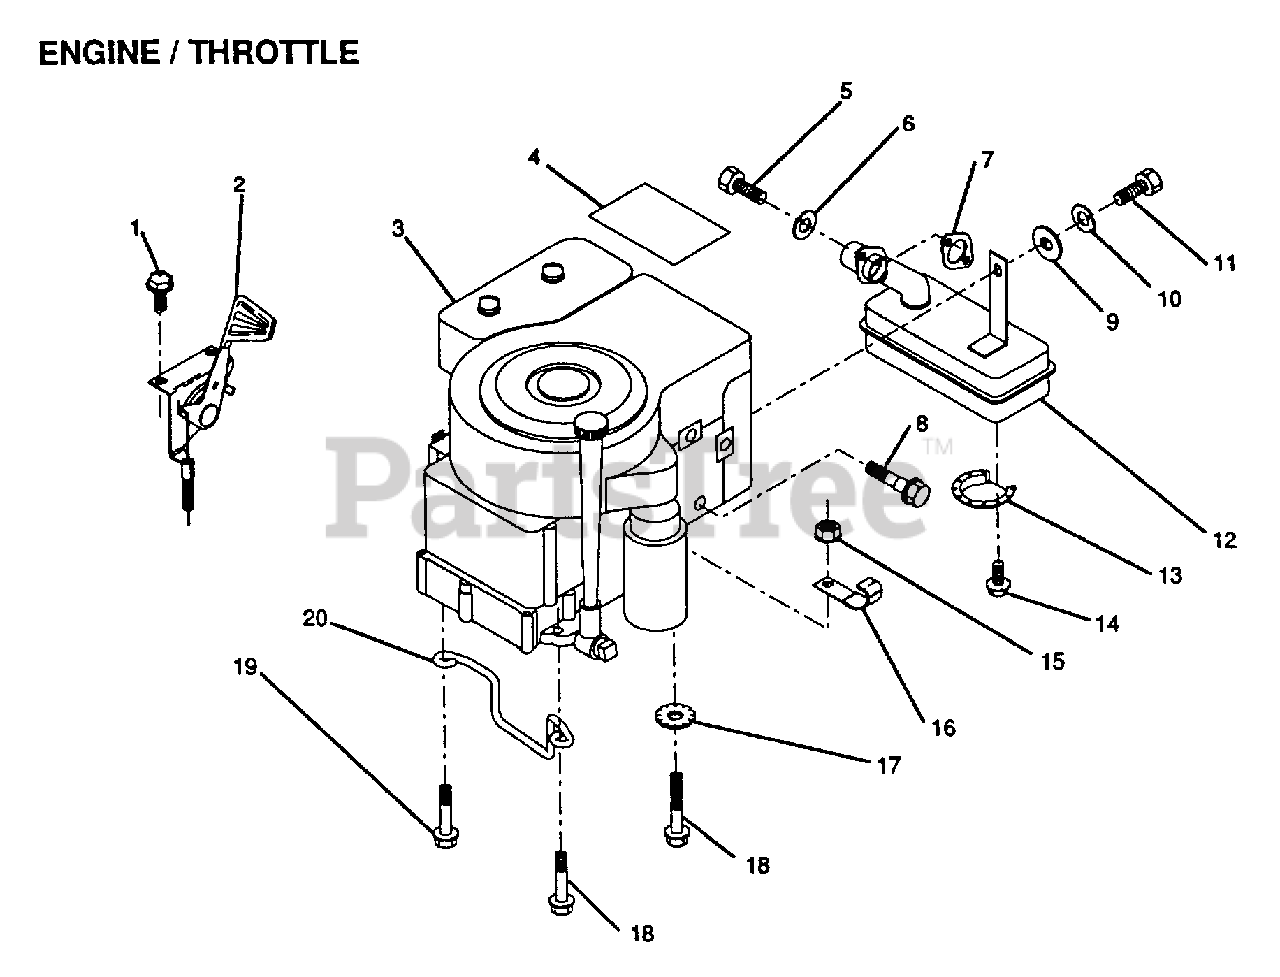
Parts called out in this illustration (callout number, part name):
1	SCREW
3	ENGINE BRIGGS AND STRATTON
4	DECAL.ENG.271967
5	SCREW
6	LOCKWASHER
8	BOLT T
10	LOCKWASHER
13	DEFLECTOR.222573
15	NUT
16	CLIP T
17	LOCKWASHER
18	SCREW LT
19	SCREW LT
